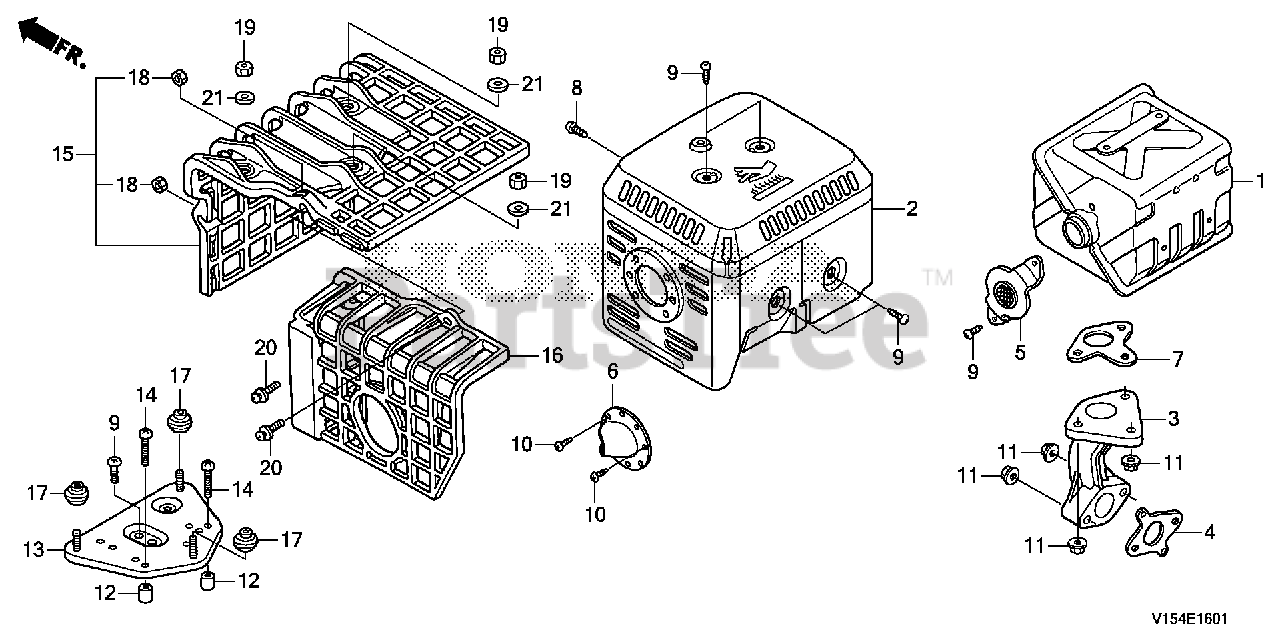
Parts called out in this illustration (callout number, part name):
1	MUFFLER
2	PROTECTOR, MUFFLER
4	GASKET, EX. PIPE
5	FLANGE, BAFFLE
6	CAP, MUFFLER
7	GASKET, MUFFLER (NIPPON LEAKLESS)
7	GASKET, MUFFLER (THAI LEAKLESS)
8	SCREW, TAPPING (6X10)
9	SCREW, TAPPING (5X8)
10	SCREW, TAPPING (4X6)
11	NUT, FLANGE (8MM)
12	COLLAR, AIR CLEANER HOUSING
13	BASE COMP
14	SCREW, TAPPING (5X25)
15	CVR, MUFF PROTECTOR
16	COVER, RR.
17	SPACER, MUFFLER COVER
18	NUT, U (6MM)
19	NUT, HEX. (5MM)
20	SCREW-WASHER (6X20)
21	WASHER, PLAIN (5MM)
